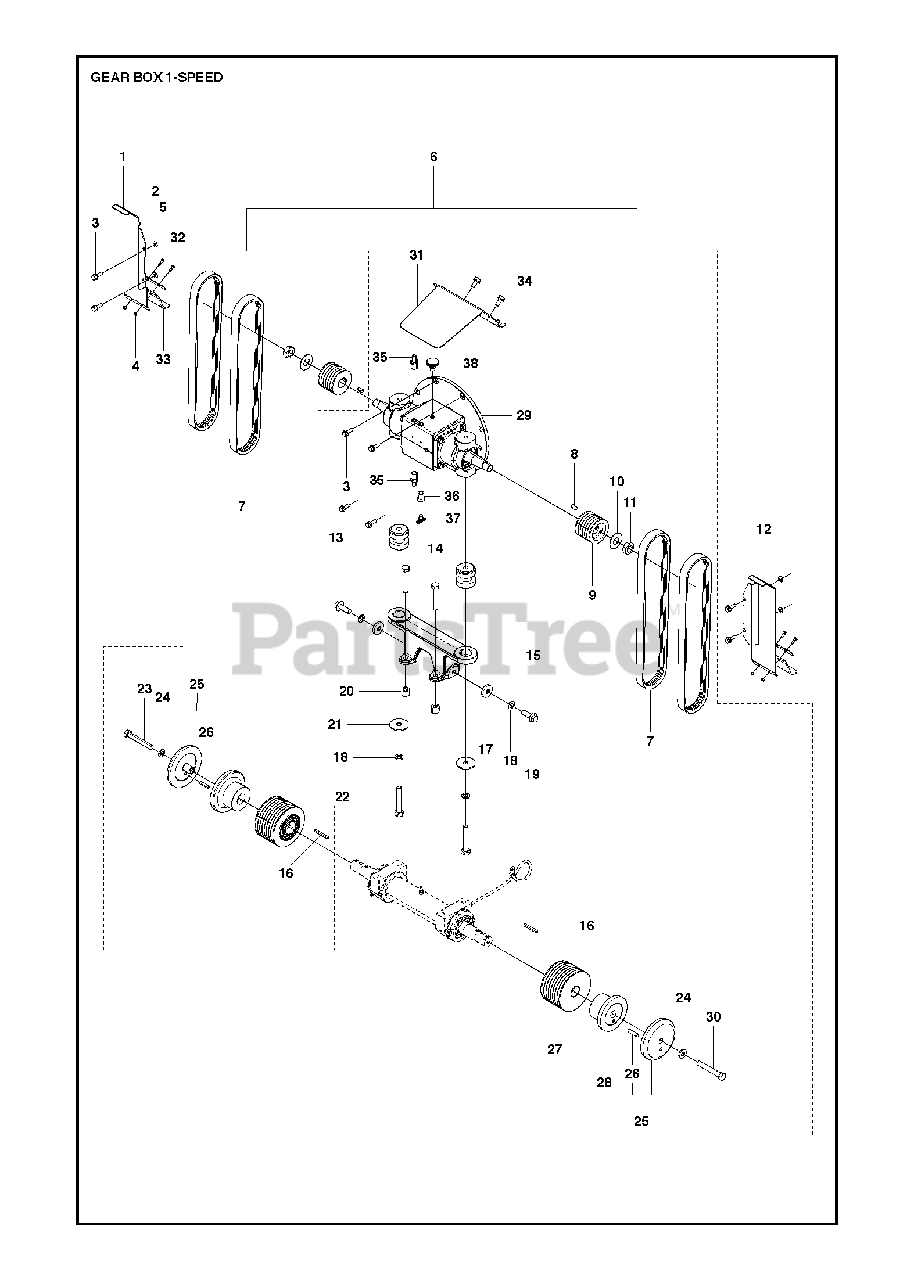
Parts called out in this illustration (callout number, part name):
2	WASHER
4	HEXAGON LOCKING NUT
13	SILENBLOC E/FS1200T PO
29	RIGHT ANGLE GEARBOX.SAE 5.BLCK
